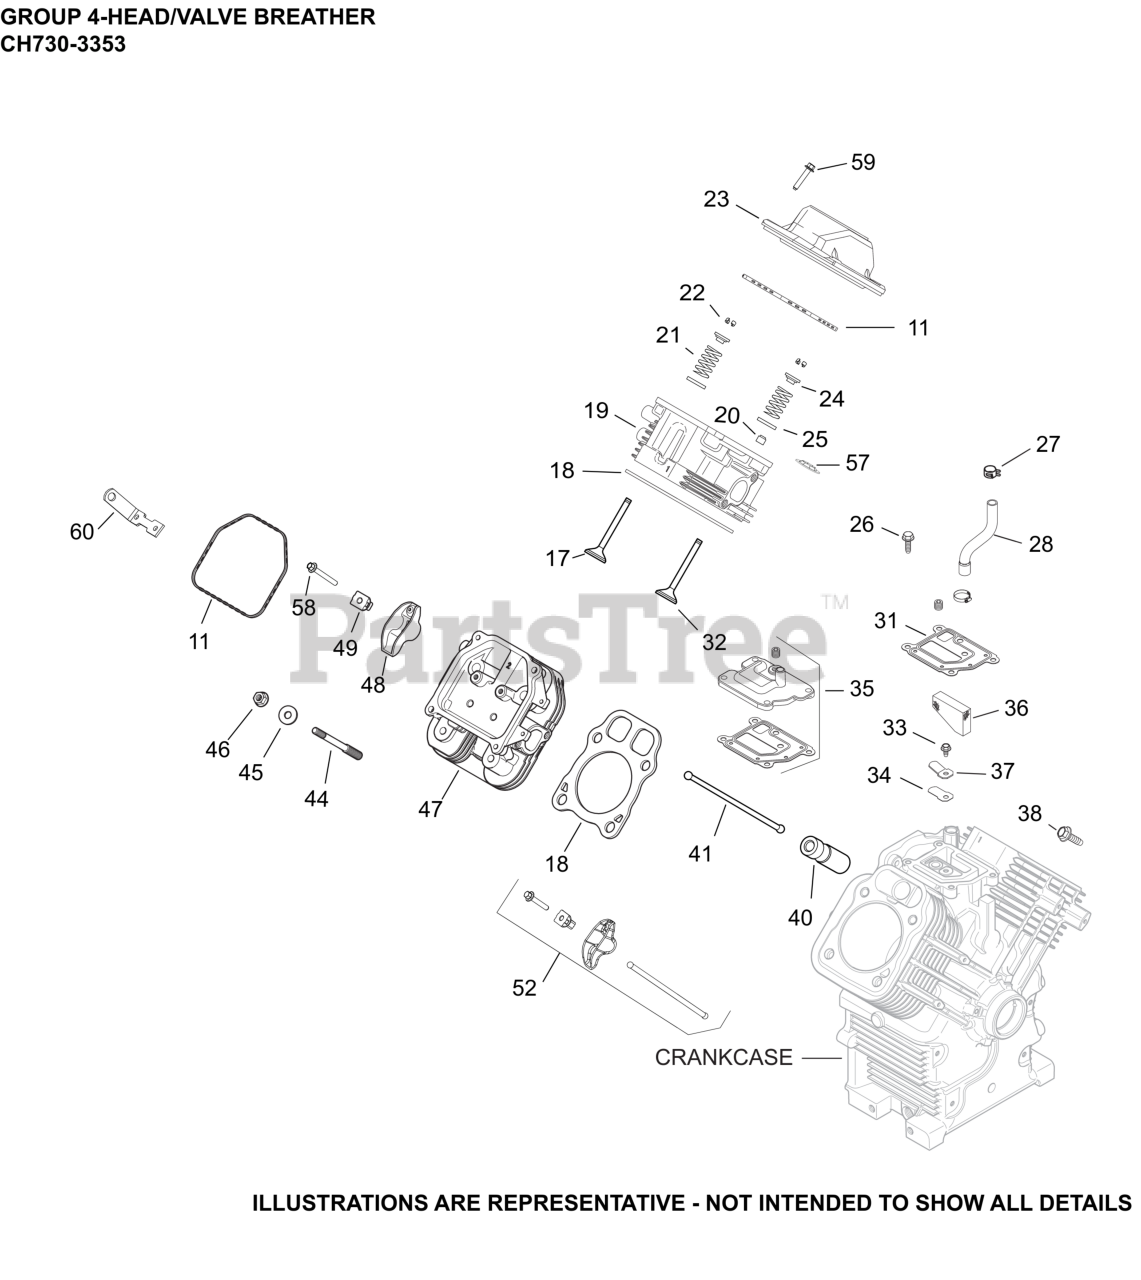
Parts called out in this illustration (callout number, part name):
11	O-RING (YELLOW), VALVE CO
17	VALVE, EXHAUST
17	VALVE, EXHAUST (.25)
18	KIT, GASKET CYLINDER HEAD
19	KIT, CYLINDER HEAD (#1)-(#2481803S)
20	SEAL, VALVE BAND
21	SPRING, VALVE
22	KIT, RETAINER
23	KIT, VALVE COVER-PLAIN (PLASTIC)
24	CAP, VALVE SPRING
25	RETAINER, SPRING
26	SCREW, THREAD FORMING
27	SPRING CLAMP, HOSE
28	KIT, BREATHER HOSE AND CLAMP
31	GASKET, BREATHER
32	VALVE, INTAKE (STD)
32	VALVE, INTAKE (.25)-(#DSC)
33	SCREW, FLG THD FRM M5X.8X10
34	REED, BREATHER
35	KIT, BREATHER ASSEMBLY
36	FILTER, BREATHER
37	RETAINER, REED
38	SCREW, THREAD FORMING
40	LIFTER, VALVE HYDRAULIC-USE 25 351 11-S
41	ROD, PUSH
44	STUD, M8X1.25
45	WASHER, FLAT 8.6 MM
46	NUT, FLG M8X1.25
47	KIT, CYLINDER HEAD (#2)-(#2481804S)
48	ARM, ROCKER
49	PIVOT, ROCKER ARM
52	KIT, VALVE TRAIN
57	RETAINER, VALVE GUIDE (KM)
58	SCREW, HEX FLANGE
59	SCREW, HEX FLANGE (M6 X 31.625 DOG PT)
60	STRAP, LIFTING
